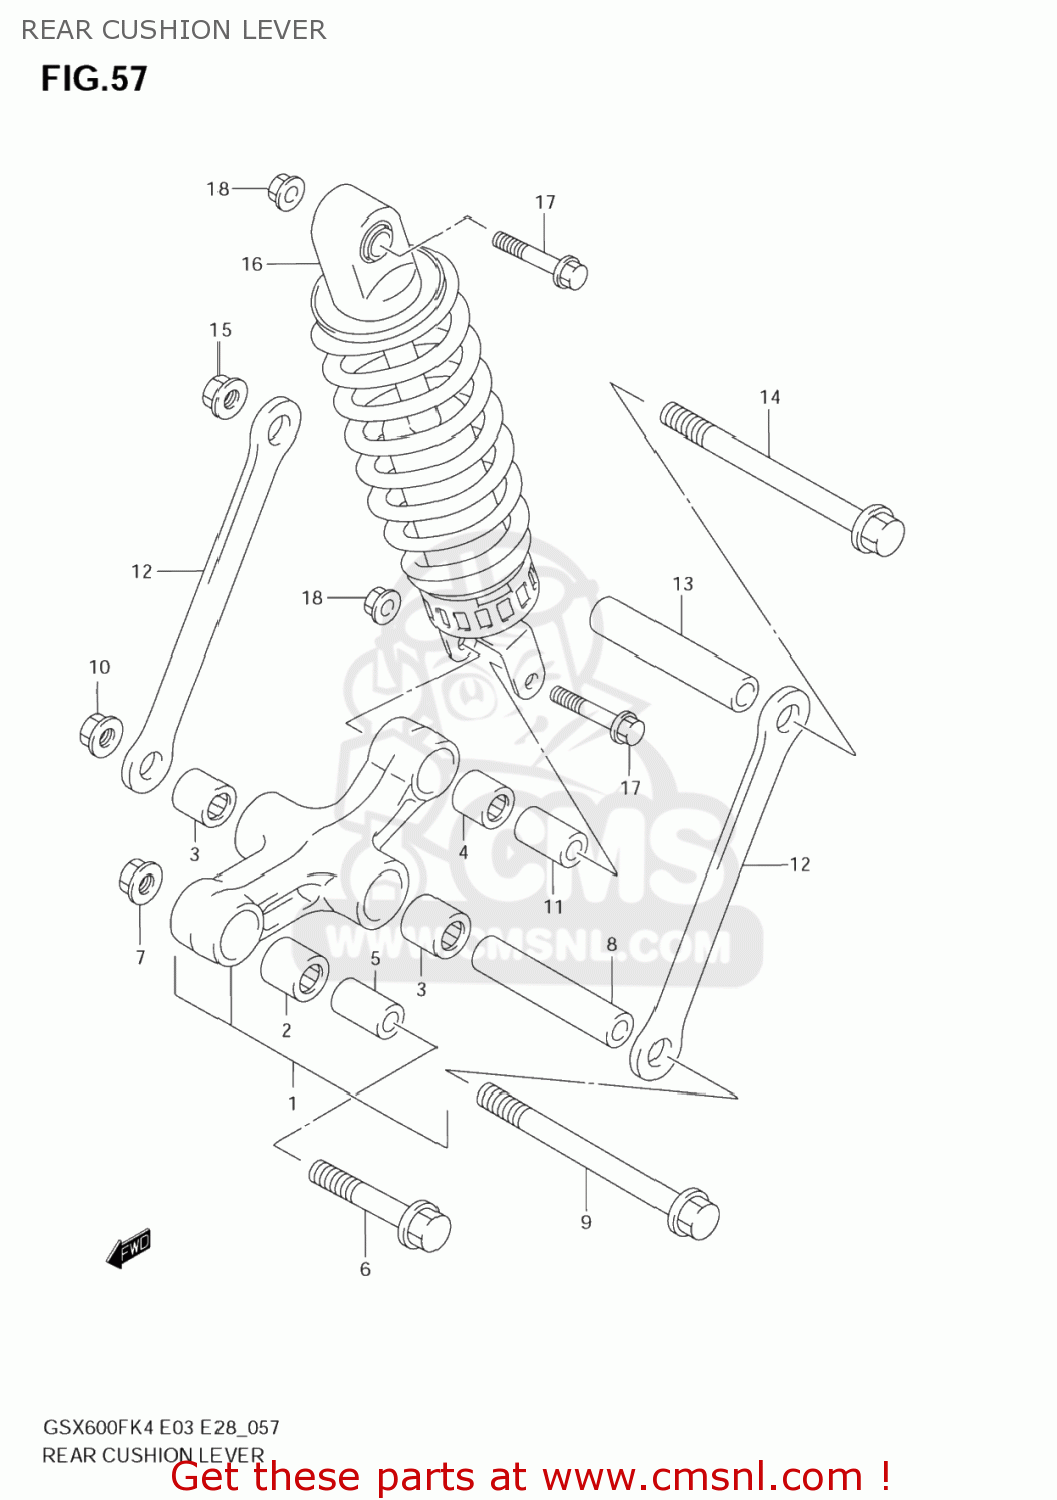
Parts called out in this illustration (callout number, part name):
1	LEVER SET,RR CUSHION
2	BEARING(20X27X30)
3	BEARING(20X27X23.5)
4	BEARING(17X24X26)
5	SPACER(14X20X34)
6	BOLT(14X62)
7	NUT
8	SPACER,RR CUSHION ROD
9	SHAFT,RR CUSHION ROD
10	NUT
11	SPACER,RR CUSHION LEVER
12	ROD,RR CUSHION
13	SPACER,RR CUSHION ROD
14	SHAFT,RR CUSHION ROD
15	NUT
16	ABSORBER ASSY,RR SHOCK
17	BOLT(10X52)
18	NUT
